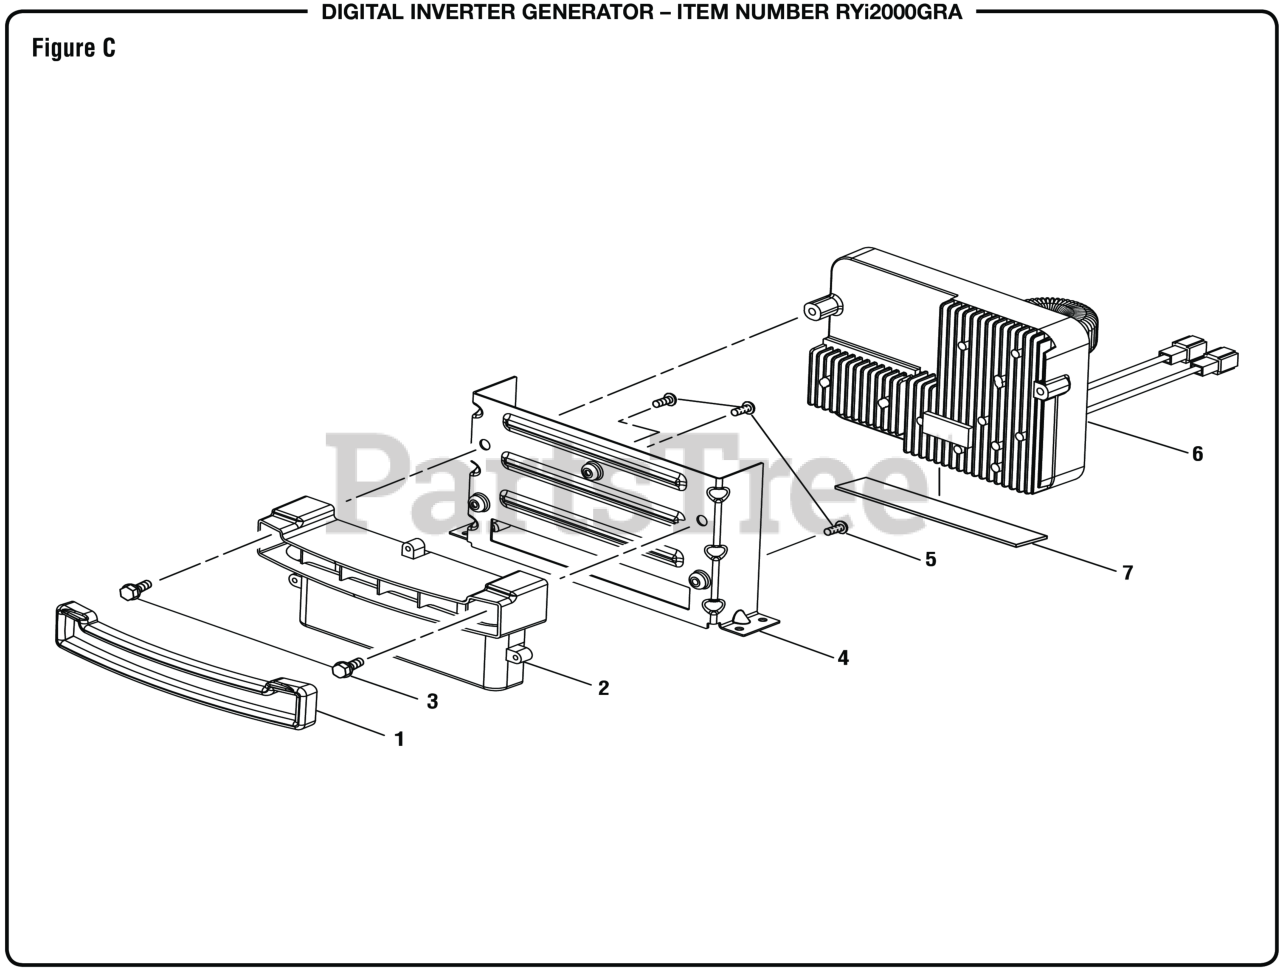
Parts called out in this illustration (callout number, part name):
1	Edge Trim Rubber
2	Baffle (Engine Intake)
3	Bolt (M6 x 12 mm, Hex Hd.)
4	Inverter Module Bracket
5	Screw w/Washer (M4 x 10 mm, T20 Torx Button Hd.)
6	Inverter Module
7	Rubber Pad
